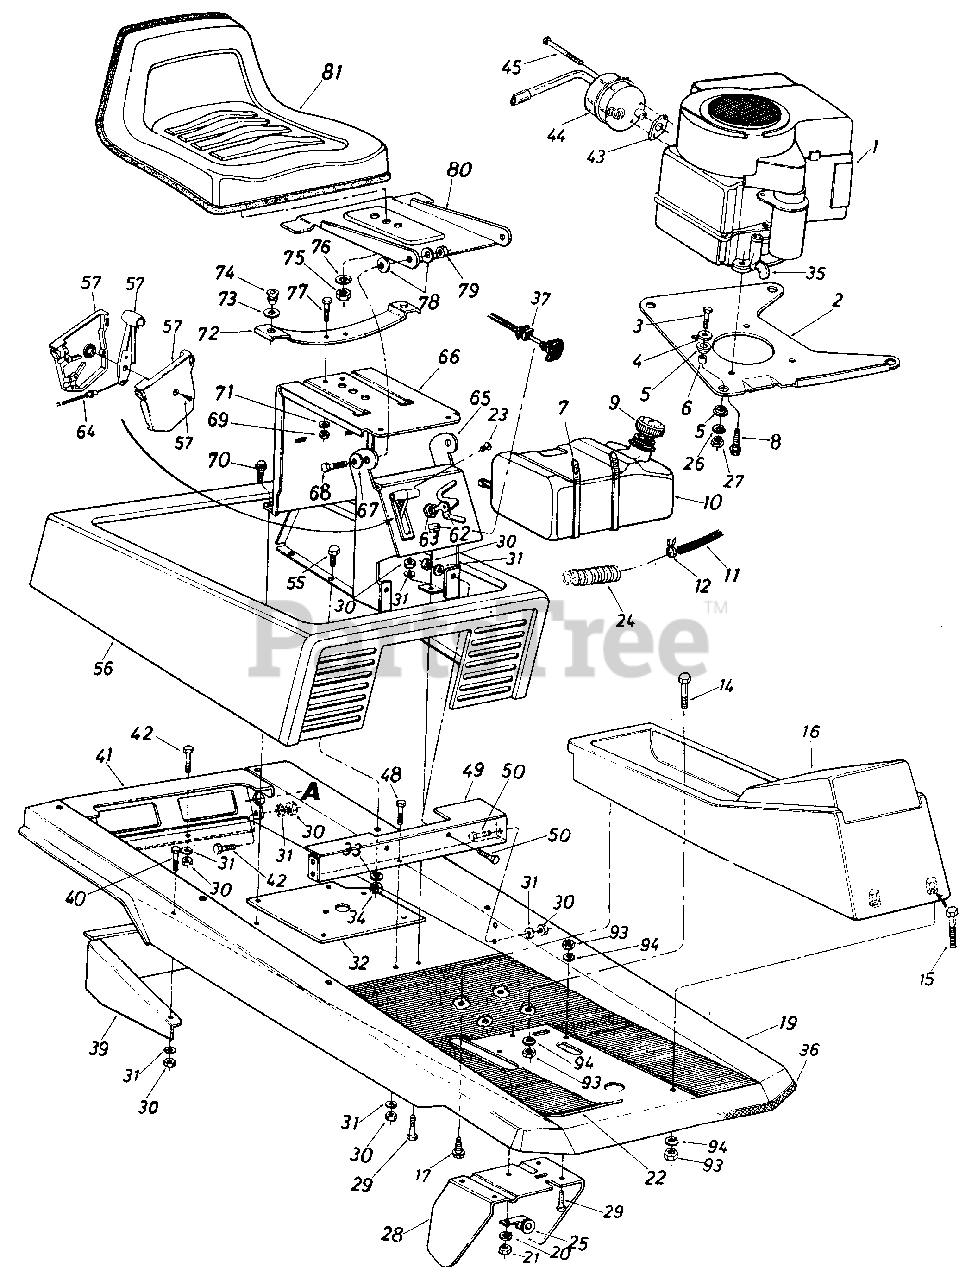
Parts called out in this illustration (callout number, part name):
1	Engine
2	Engine Mounting Plate
3	Hex Bolt 5/16-24 x 1.25" Lg.
4	Fl-Wash. .330" I.D. x 1.125" O.D.
5	Engine Mounting Grommet
6	Spacer .315" I.D. x .50" O.D. x.520" Lg.
7	Cable Tie 30.6 Lg.
8	Hex Wash. Hd. Self-Tap Scr. 3/8-16 x 1.25" Lg.
9	Gas Gauge
10	Fuel Tank
11	Gas Line
12	Hose Clamp .406" Dia.
14	Hex Bolt 5/16-18 x 1.75" Lg.
15	Hex Bolt 5/16-18 x 2.0" Lg.
16	Front Console
17	Plastite Scr. 5/8 x 1 .25"
19	Main Frame
20	L-Wash. 5/16" I.D.
21	Hex Nut 5/16-18 Thd.
22	Floor Mat
23	Truss Mach. AB-Tap Scr. #10 x .50" Lg.
24	Convoluted Conduit
25	Clamp
26	L-Wash. 5/16" I.D.
27	Hex Nut 5/16-24 Thd.
28	Clutch-Brake Pedal Ass'y.
29	Hex Bolt 5/16-18 x .75" Lg.
30	Hex Nut 5/16-18 Thd.
31	L-Wash. 5/16" I.D.
32	Mounting Brkt. Variable Speed Pulley
33	L-Wash. 1/4" I.D.
34	Hex Nut 1/4-20 Thd.
35	90ø Elbow Male To Female
36	Trim Strip 18" Lg.
37	Choke Control
39	Transaxle Support Ass'y.
40	Hex Bolt 5/16-18 x .75" Lg.
43	Exhaust Gasket
44	Muffler Ass'y.
45	Shld. Bolt
49	Seat Support & Frame Brkt.
50	Hex Bolt 5/16-18 x .75" Lg.
55	Hex Bolt 1/4-20 x .50" Lg.
56	Engine Cover Ass'y.
57	Throttle Control Box Ass'y.
62	Ignition Key
63	Ignition Switch
64	Throttle Control Wire
65	Front Seat Bracket
66	Rear Seat Bracket
67	Bell-Wash. .345" I.D. x .88" O.D.
68	Hex Bolt 5/16-18 x .75" Lg.
69	Hex Nut 5/16-18 Thd.
70	Hex Self-Tap Scr. 5/16-18 x .75" Lg.
71	L-Wash. 1/4" I.D.
72	Seat Spring
73	Fl-Wash. .531" I.D. x .930" O.D.
74	Grommet
75	Hex Nut 1/2-13 Thd.
76	L-Wash. 1/2" I.D.
77	Hex Bolt 1/4-20 x .75" Lg.
78	Bell-Wash. .345" I.D. x .88" O.D.
79	Hex Cent. L-Nut 5/16-18 Thd.
80	Seat Pivot Bracket
81	Seat Ass'y. Comp.
93	Hex Nut 5/16-18 Thd.
94	L-Wash. 5/16" I.D.
